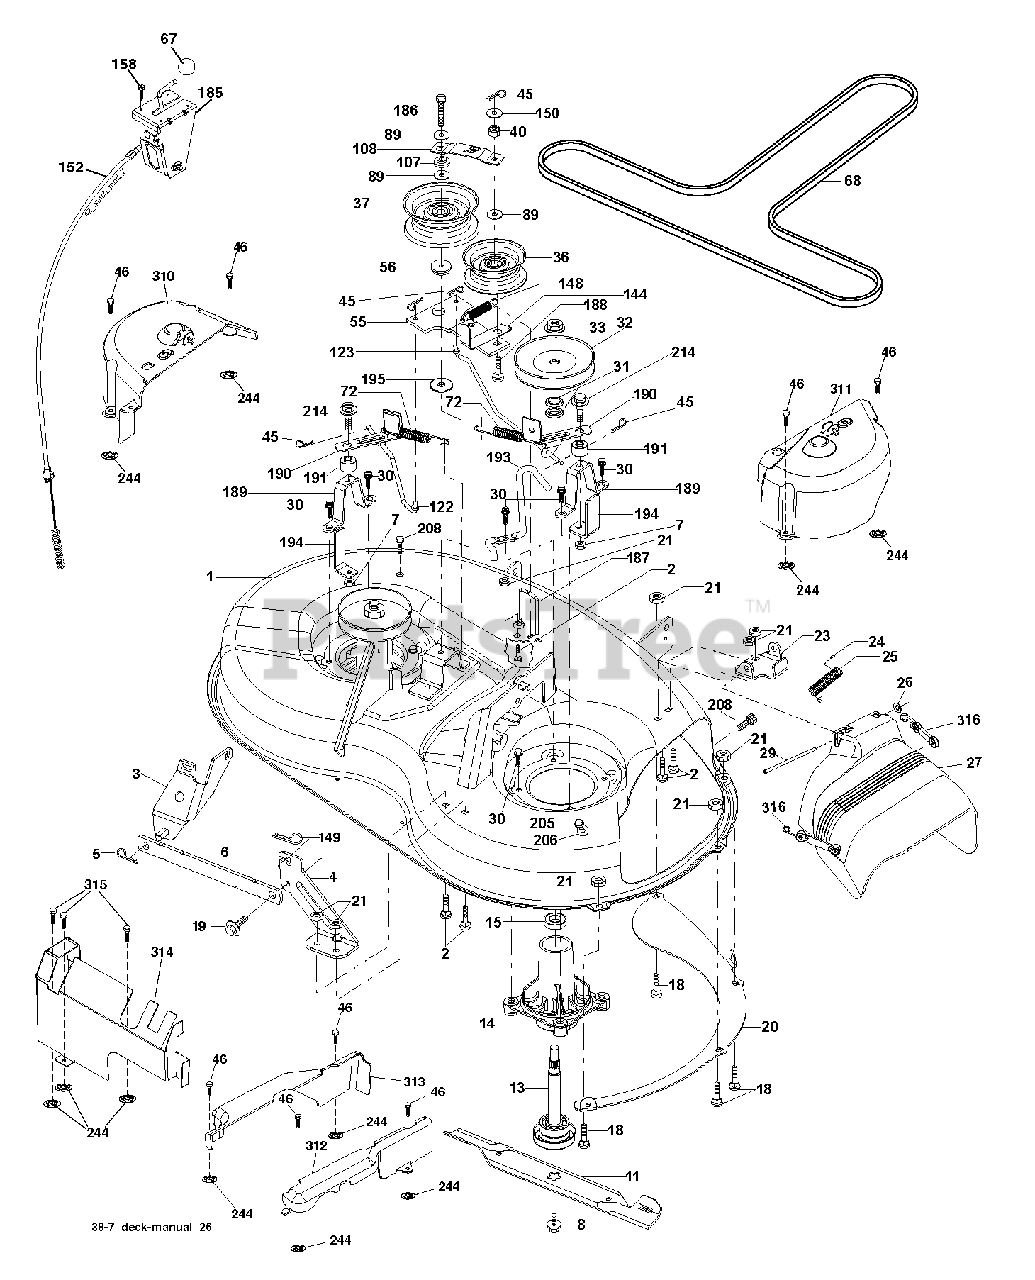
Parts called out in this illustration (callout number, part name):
1	DECK.WELDMENT.38"2005
2	BOLT
3	BRKT ASM SWAY BAR
4	BRACKET DECK SWAY BAR 38"/42"
5	RETAINER-SPRNG RB
6	BAR SWAY DECK
7	NUT.71038.31-18.HEX.NYLOCK
8	BOLT.WASHER.ASM.7/16-2
11	BLADE 38" PREMIUM
13	SHAFT.ASM.MDRL.N/GREASE.38
14	HOUSING MANDREL
18	BOLT
19	BOLT SHD 5/16-18
20	BAFFLE VORTEX
21	LOCKNUT
23	BRKT.DEFLECTOR.38"2005+
24	CAP-SLEEVE LT
25	SPRING.TORSION.DEFLECT
26	NUT PUSH M
29	ROD.HINGE
30	SCREW, WASHER HEAD
31	WASHER.SPACER.MANDREL
32	PULLEY MANDREL
33	NUT.FLANGE.LOCK.TOP
36	FLAT IDLER PULLEY
37	PULLEY.IDLER.FLAT.UNPLATED
40	LOCKNUT
45	RETAINER M
46	SCREW.1/4-20X5/8
55	IDLER ARM
56	SPACER.RETAINER.MOWER
67	KNOB T (3/8 HOLE)
68	V-BELT.MOWER.38"2005+
72	SPRING.BRAKE.RETURN.38"
89	WASHER
107	SPACER.IDLER.ARM
108	STIFFENER.IDLER.ARM
122	ROD, BRAKE LH LINK
123	LINK.BRAKE.38"RIGHT
144	KEEPER BELT
148	IDLER RETURN SPRING
149	SPRING.RETAINER.YELLOW.ZINC
150	WASHER LT
152	CABLE.CLUTCH.38".SERVICE
158	SCREW
185	HEAD ASM. CABLE CLUTCH
186	SCREW.HXWSH.3/8
187	KEEPER BELT
188	BOLT, CARRIAGE IDLER
189	STAND, BRAKE
190	ARM, BRAKE
191	SPACER, BRAKE
193	KEEPER BELT RH MANDREL
194	GUARD BRAKE
195	WASHER 12/32X2X10GA
205	SCREW
208	SCREW 3/8-16X1/2
214	BOLT/WASHER ASM 5/16-18
244	PALNUT 1/4
